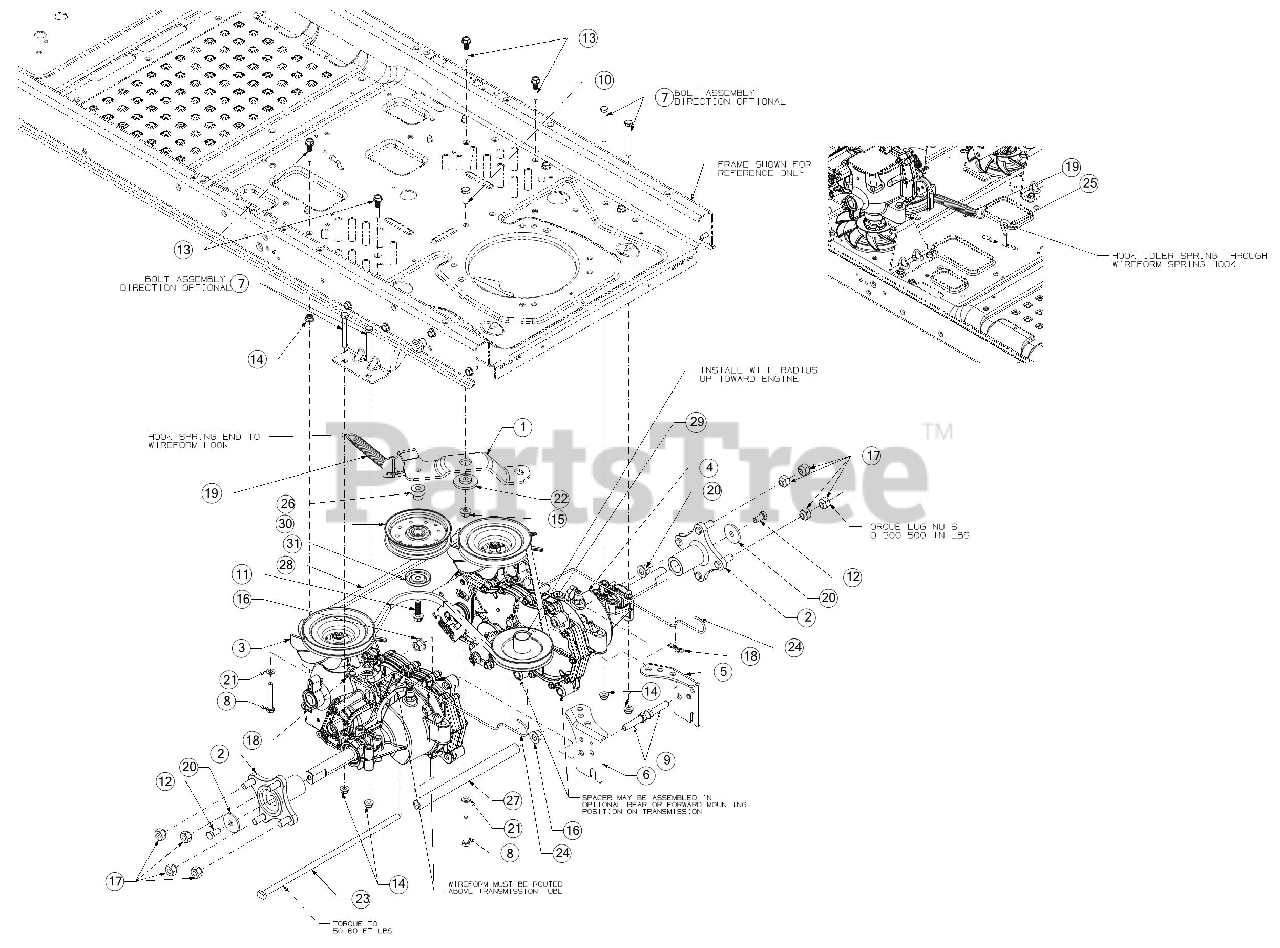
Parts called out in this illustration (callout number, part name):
1	IDLER BRACKET ASSEMBLY
2	WHEEL HUB ASSEMBLY
3	HYDRO TRANSMISSION ASSEMBLY (LH)
4	HYDRO TRANSMISSION ASSEMBLY (RH)
5	TRANSMISSION MOUNTING BRACKET (RH)
6	TRANSMISSION MOUNTING BRACKET (LH)
7	HEX SCREW 5/16-18 X 2.75
8	HEX SCREW 5/16-18 X 2.25 GR5
9	SCREW 7/16-20 X 1.75 GR 5
10	SCREW 3/8-16 X 1 GR5
11	SCREW 3/8-16 X1.250
12	SCREW 3/8-16 X .75 GR 5
13	BELT KEEPER ROD .25 X 1.585
14	FLANGE LOCK NUT 5/16-18
16	FLANGE LOCK NUT
17	LUG NUT 7/16-14
18	BOW TIE COTTER PIN 1/4-5/16
19	EXTENSION SPRING .75 DIA X 5.87 RZT/F
20	FLAT WASHER .390x1.500x.134
21	FLAT WASHER
22	SHOULDER SPACER
23	SUPPORT TUBE ROD
24	HYDRO BYPASS ROD
25	IDLER SPRING HOOK
26	SHOULDER SPACER
27	SUPPORT TUBE
28	TRANSMISSION DRIVE BELT A X 67
29	TRANSMISSION PULLEY
30	IDLER PULLEY 4.25 DIA
31	IDLER PULLEY CAP
